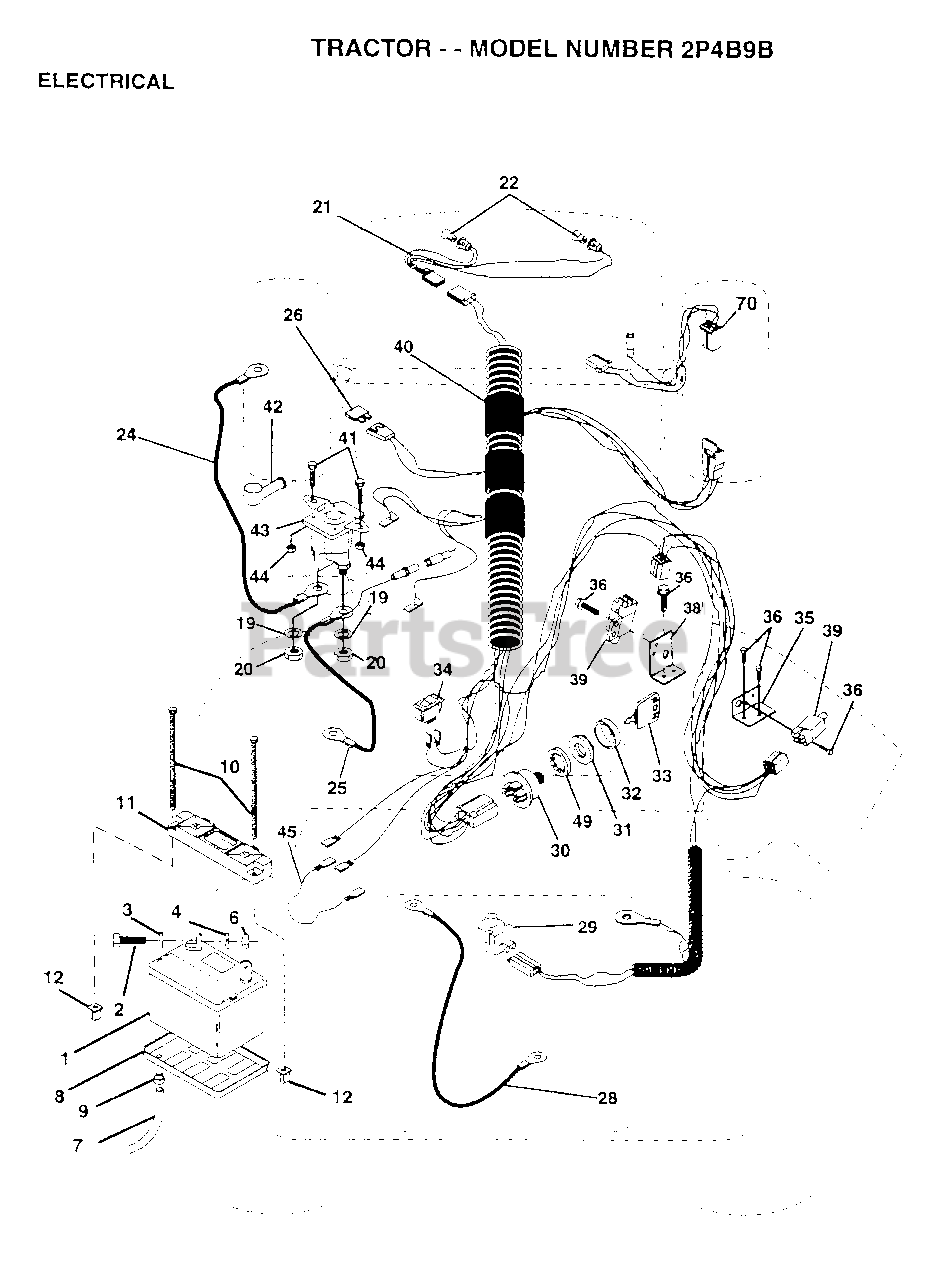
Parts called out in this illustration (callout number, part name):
2	BOLT LT
3	WASHER
4	LOCKWASHER
7	"DRAIN TU T, BATT"
8	"TRAY T, BATTERY"
9	HOSE CLAMP T
20	NUT
21	"HARNESS,LIGHT SOC"
22	HEADLAMP BULB
24	CABLE-BATTERY T
25	CABLE.6GA.22W/16W
26	FUSE HYT
28	CABLE.GRND.6GA.21
29	SWITCH SEAT
32	COVER KEY SWITCH
33	KEY MLD GEN DELTA
34	SWITCH LT
35	BRACKET LT
36	SCREW
38	BRACKET SWITCH IN
39	SWITCH INTERLOCKT
40	HARNESS.IGN.DASH.
41	BOLT.HX.1/4-20
44	NUT
45	ADAPTER AMMETER
49	LOCKWASHER
55	SCREW LT
70	HARNESS ENG DUAL
